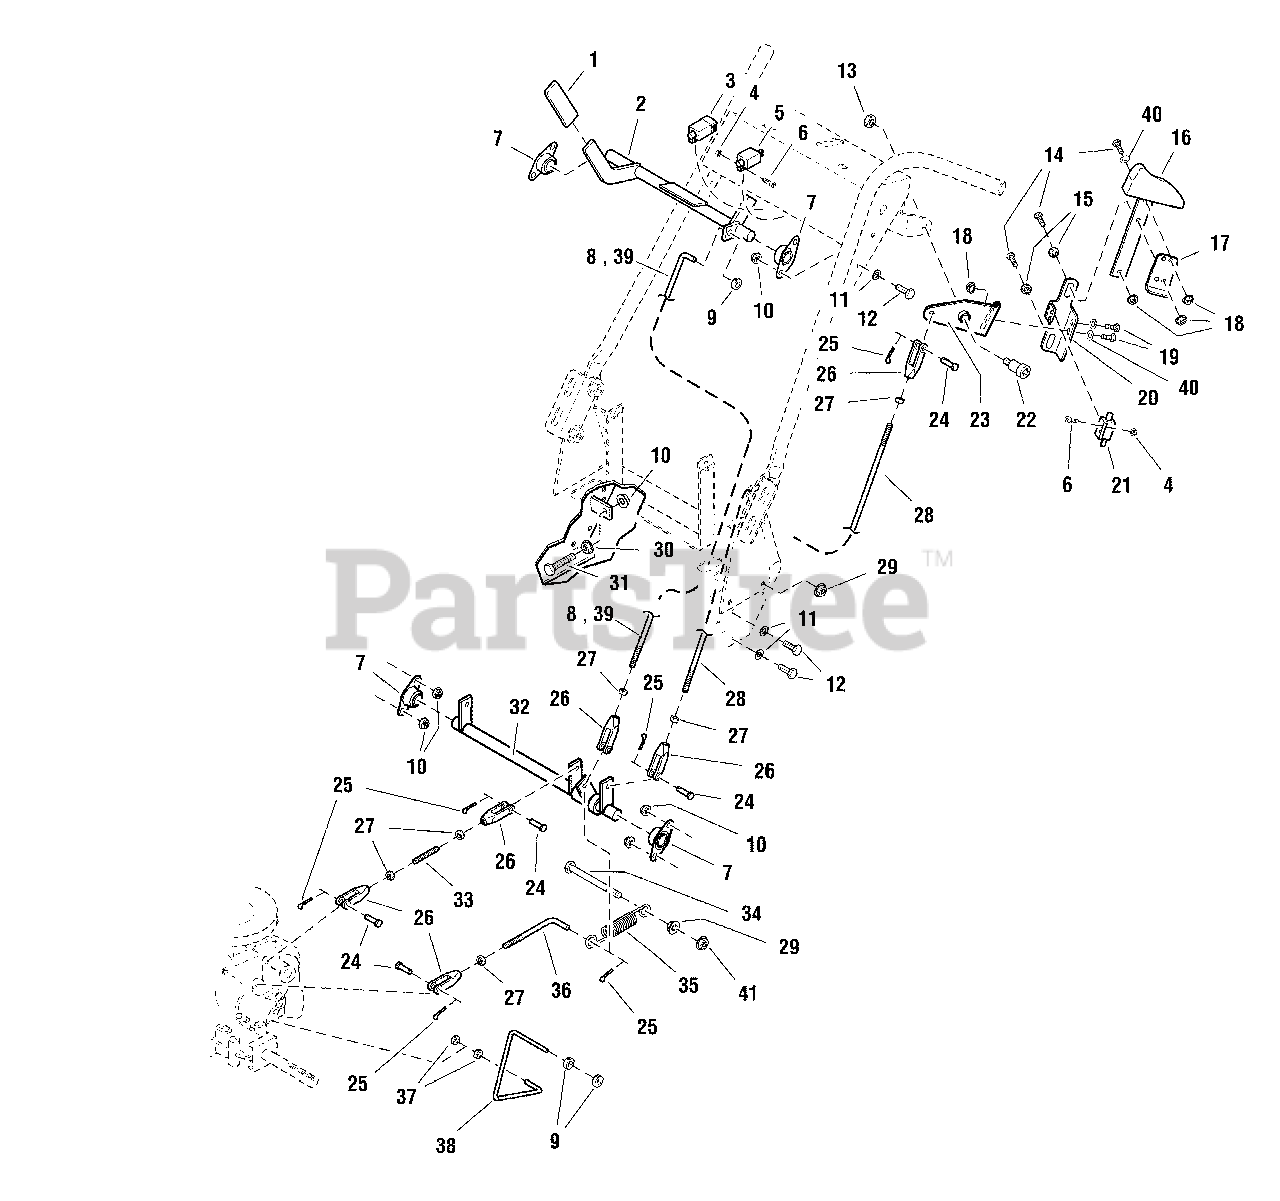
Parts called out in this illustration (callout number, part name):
2	BRAKE HANDLE SHAFT ASSEMBLY
3	SWITCH, Plunger, NO/NO
4	NUT, #10-24 Hex
5	SWITCH, Plunger, NC
6	SCREW, #10-24 x 1/2
7	BEARING, Flange
8	BRAKE ROD
9	COLLAR, 5/16" Set
10	NUT, 5/16-18 Hex Nylon Lock
11	WASHER, 5/16" SAE
12	BOLT, 5/16-18 x 3/4
13	NUT, 3/8-16 Hex Side Lock
14	BOLT, 1/4-20 X 1", GD
15	SLIDE SPACER
16	CONTROL HANDLE, LH
16	CONTROL HANDLE, RH
17	SWITCH ACTUATOR
18	NUT, 1/4-20 Hex Serrated Flange
19	BOLT, 1/4-20 x 3/4
20	HANDLE MOUNT, LH
20	HANDLE MOUNT, RH
21	SWITCH, Plunger, NC
22	SHOULDER BOLT, 1/2 x 1
23	PIVOT CONTROL, LH
23	PIVOT CONTROL, RH
24	CLEVIS PIN, 5/16 x 1
25	COTTER PIN, 3/32" x 3/4"
26	CLEVIS, 5/16-24, Plastic
27	NUT, 5/16-24 Hex
28	THUMB CONTROL ROD
29	NUT, 3/8-16 Hex Serrated Flange
30	NUT, 5/16-18 Hex Small Serrated Flange
31	BOLT, 5/16-18 x 1-3/4 TFL
32	CONTROL SHAFT ASSEMBLY
34	BOLT, 3/8-16 x 4
35	SPRING, Extension
36	BRAKE LINKAGE ROD
37	COLLAR, Set, 1/4"
38	DUMP VALVE ROD
39	ROD, PARKING BRAKE LINKAGE
40	WASHER, 1/4 SAE (5025154)
41	NUT, 3/8-16 HEX NYLOCK FLANGE
